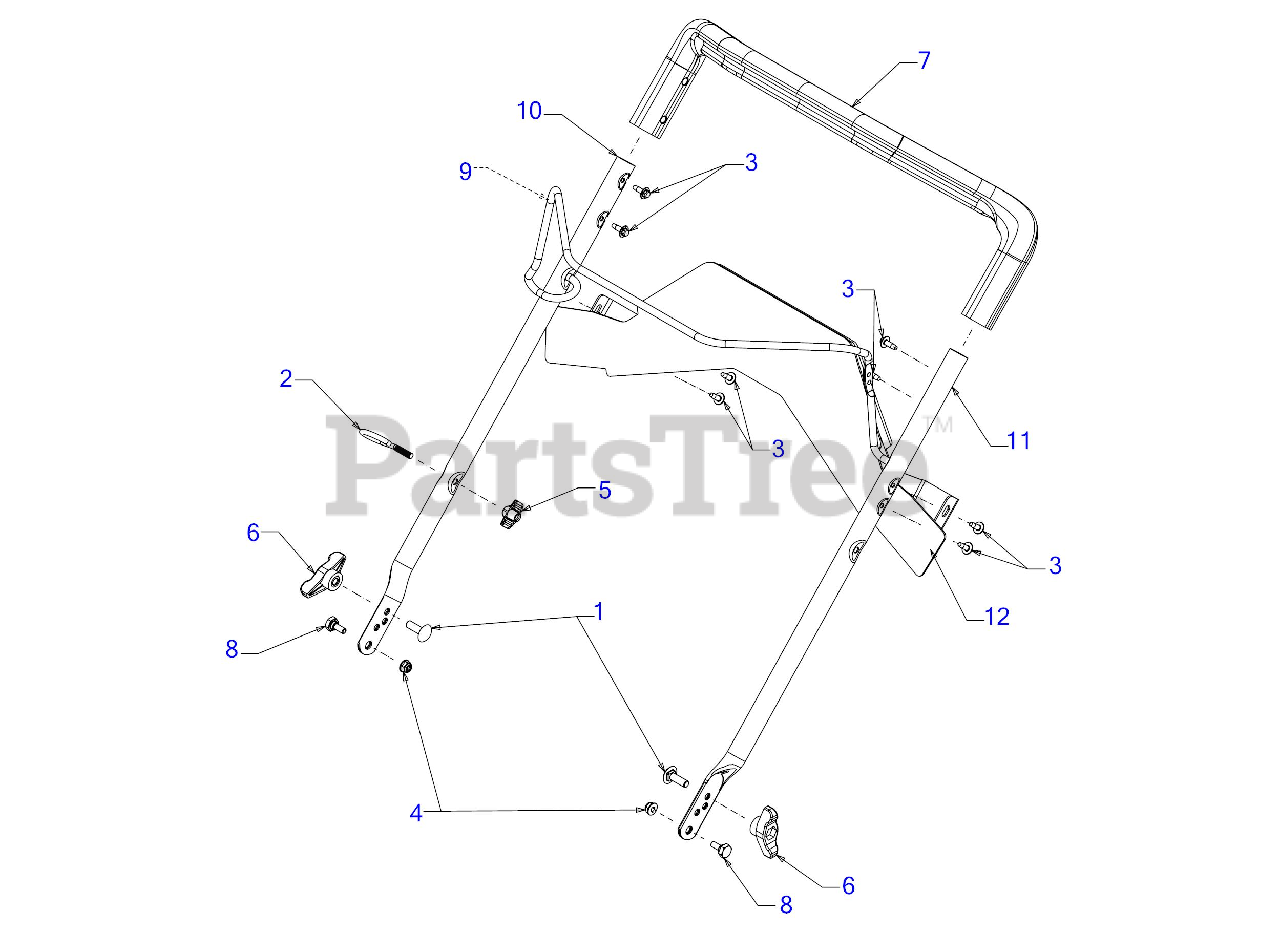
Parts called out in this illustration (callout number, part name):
1	SCREW 5/16-18 x 1.00 GR5
2	EYEBOLT 1/4-20
3	SCREW M6-1 x .625
4	FLANGE LOCK NUT
5	HANDLE KNOB
6	WING KNOB 5/16-18
7	HANDLE GRIP
8	SHOULDER SCREW
9	DRIVE BAIL
10	UPPER HANDLE (RH)
11	UPPER HANDLE (LH)
12	HANDLE PANEL
